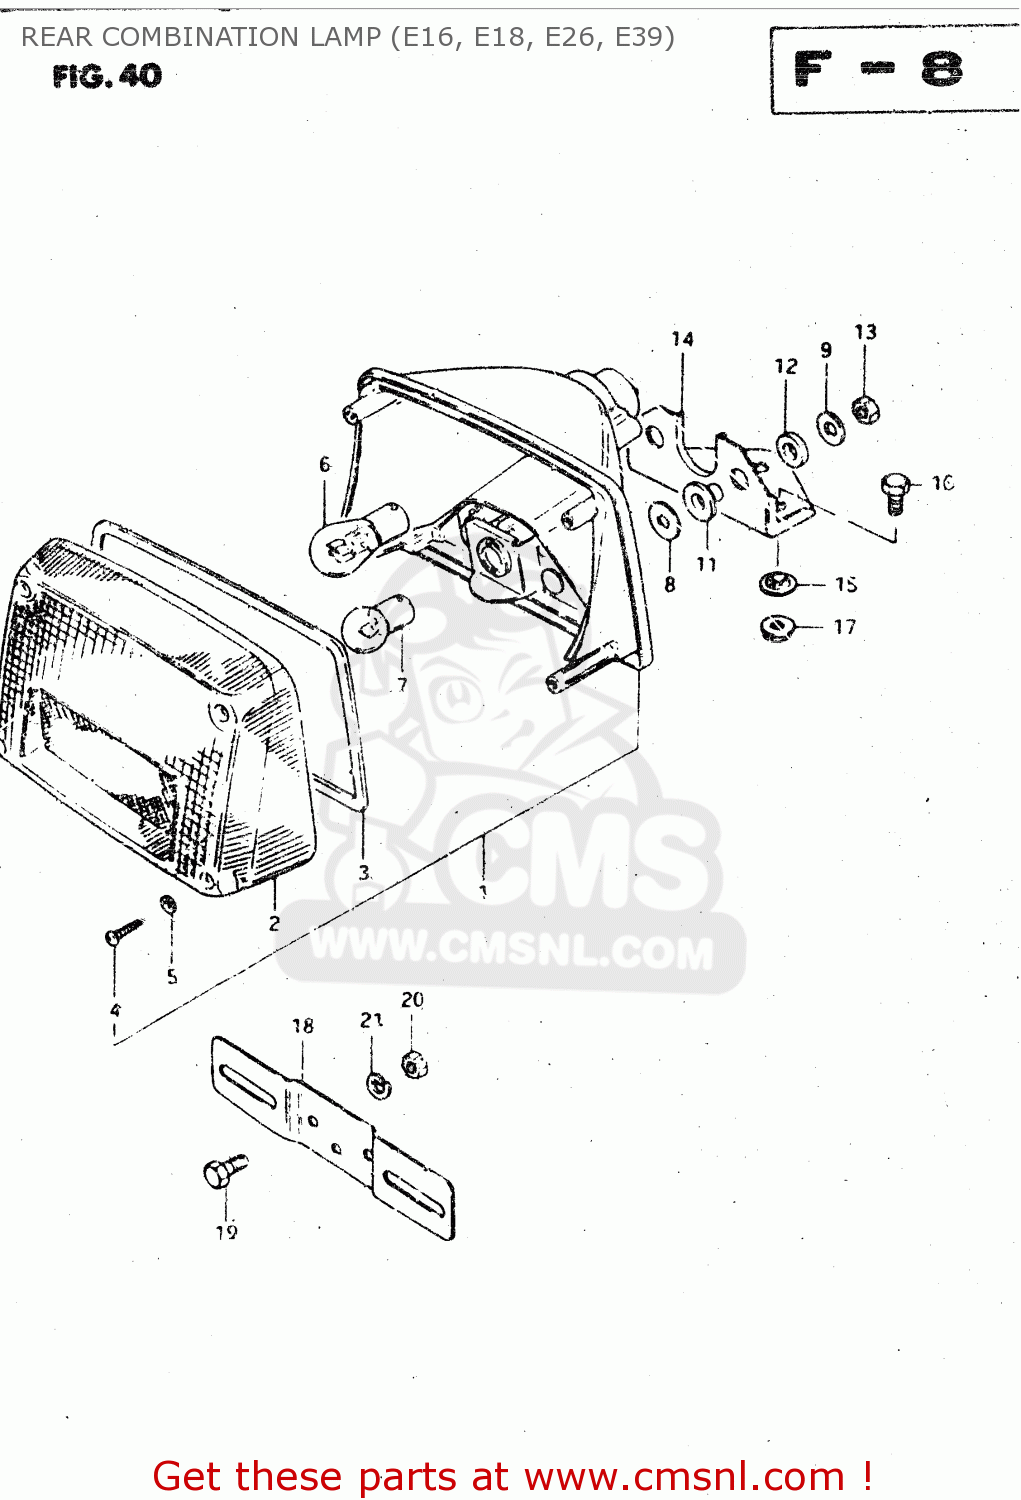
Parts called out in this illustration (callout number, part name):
1	LAMP ASSY, TAIL
2	LENS
3	GASKET (NAS)
4	SCREW,REAR COMBINATION LAMP
5	GASKET (NAS)
6	BULB 12V21/5W
7	BULB
8	WASHER
9	WASHER(6,5X22X1.6)
10	SPACER(6.1X9X7.5)
11	CUSHION
12	CUSHION
13	NUT 6MM
14	BRACKET,RR COMBINATION LAMP
15	WASHER
16	BOLT, UPPER
17	NUT 6MM
18	PLATE,RR LICENSE
19	BOLT
20	NUT
21	LOCK WASHER
